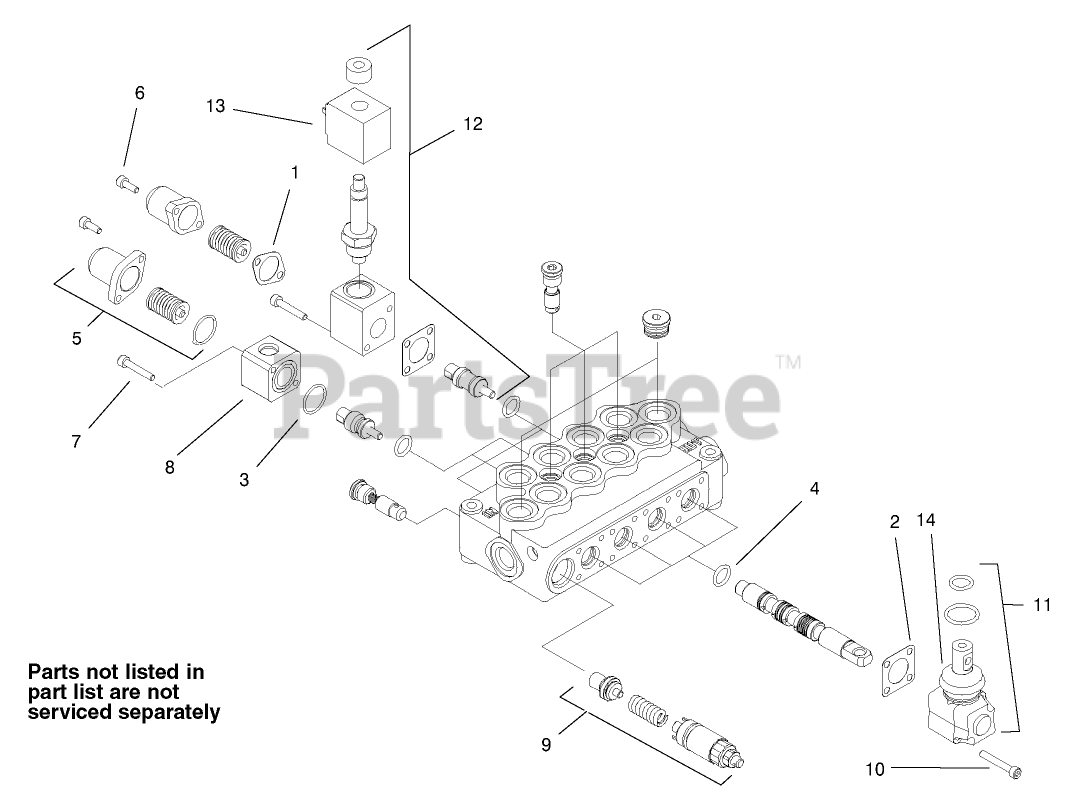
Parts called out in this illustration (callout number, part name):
3	SEAL KIT
3:1	GASKET
3:2	GASKET
5	STANDARD SPRING KIT
5	HIGH FORCE SPRING KIT
6	SCREW-CAP, END
8	BLOCK-MOUNT, SWITCH
9	VALVE-RELIEF
11	OPERATOR ASM
12	SPOOL LOCK ASM
13	COIL WITH CONNECTOR
